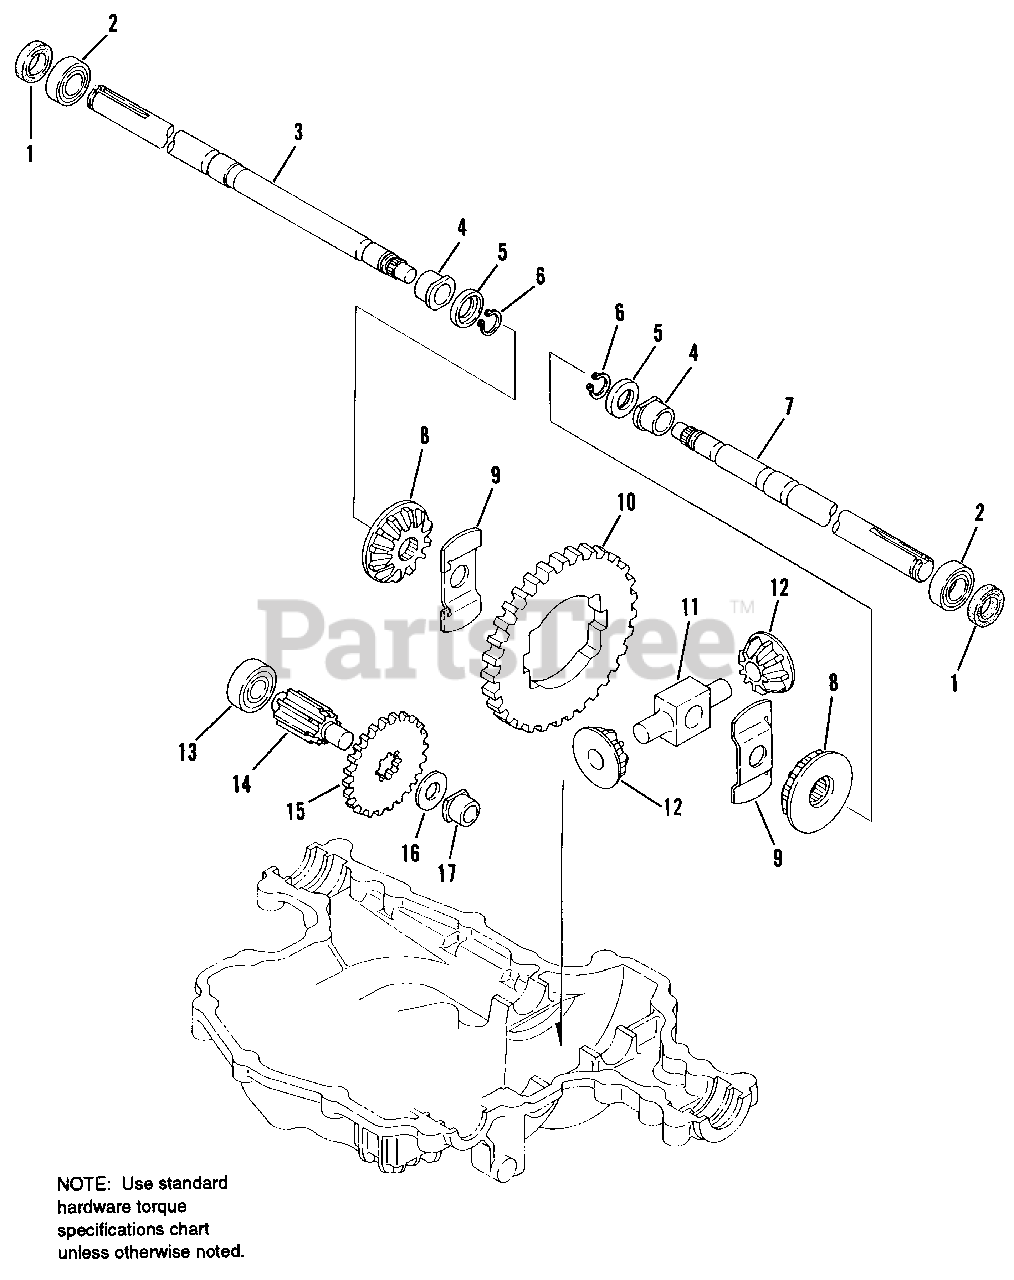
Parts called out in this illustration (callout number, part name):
3	AXLE SHAFT, Right
6	RING, Retaining
7	AXLE SHAFT, Left
8	GEAR, Differential
9	THRUST WASHER
11	SHAFT, Pinion
14	SHAFT, Final Pinion
